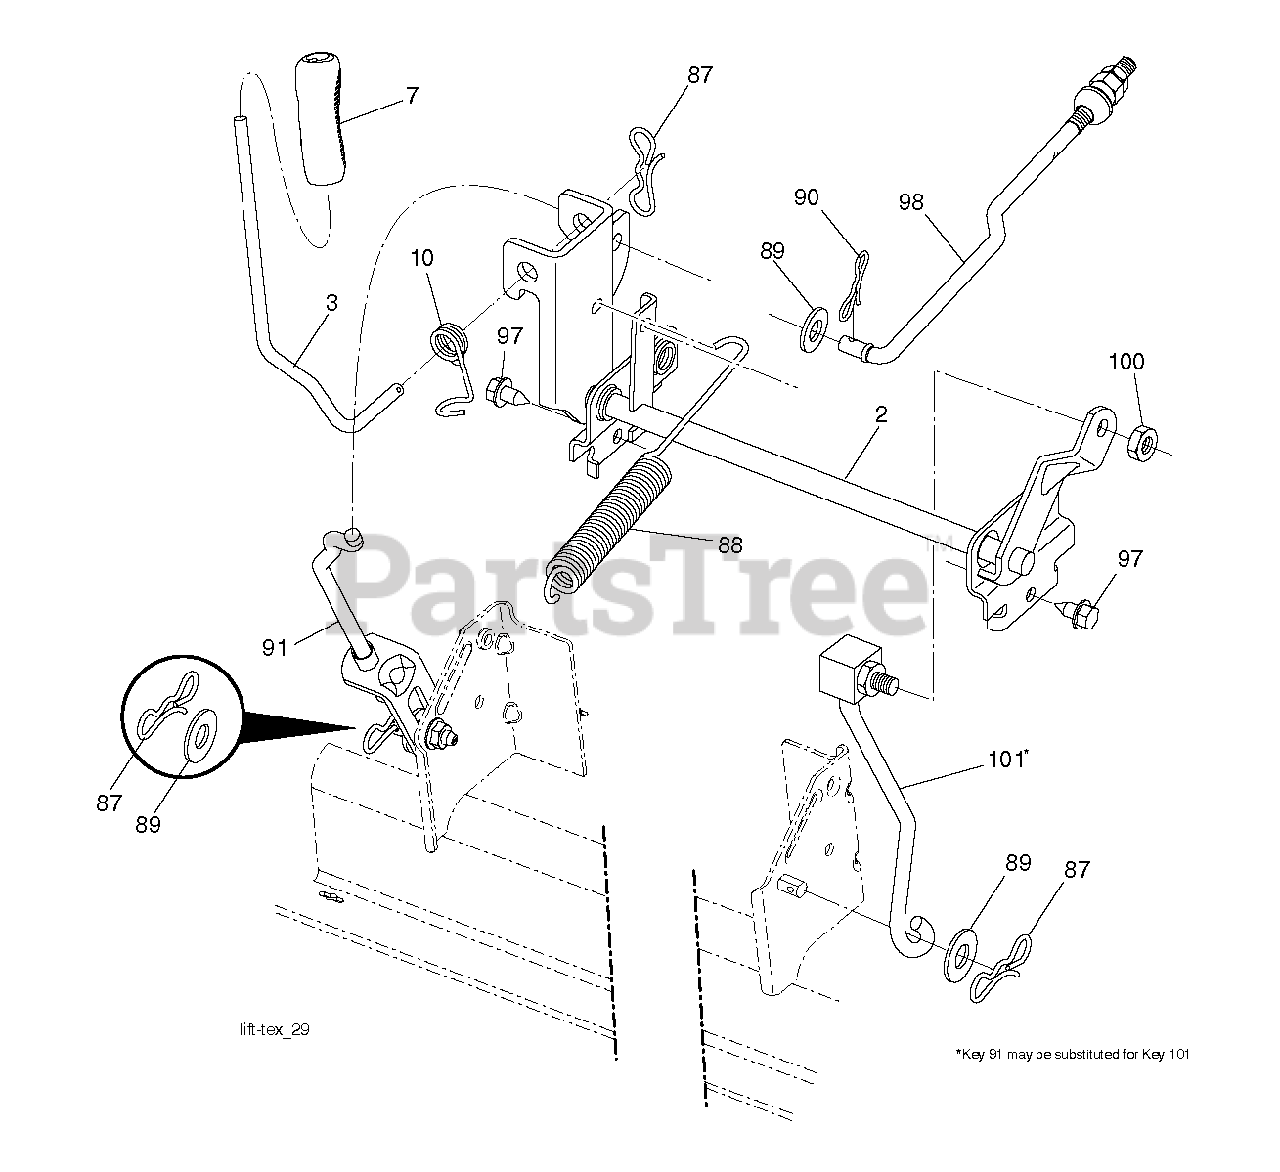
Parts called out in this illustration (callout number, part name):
2	SHAFT.ASM.CROSS.LIFT
3	LEVER.LIFT.HANDLE.LT
7	GRIP.HANDLE.LIFT.PVC.BLACK
10	SPRING.TORSION.LIFT.HANDLE
87	PIN.COTTER.7/16.BOW TI
88	SPRING.LIFT.ASSIST
89	WASHER.CLEAR.ZINC
90	PIN.COTTER.5/16.BOW TI
91	LINK.ASM.LIFT.REAR
97	SCREW, 3/8-16X3/4
98	LINK.ASM.SUSP.FRONT.MW
100	LOCKNUT
101	LINK.ASM.LIFT.FIXE.38/42/46"
